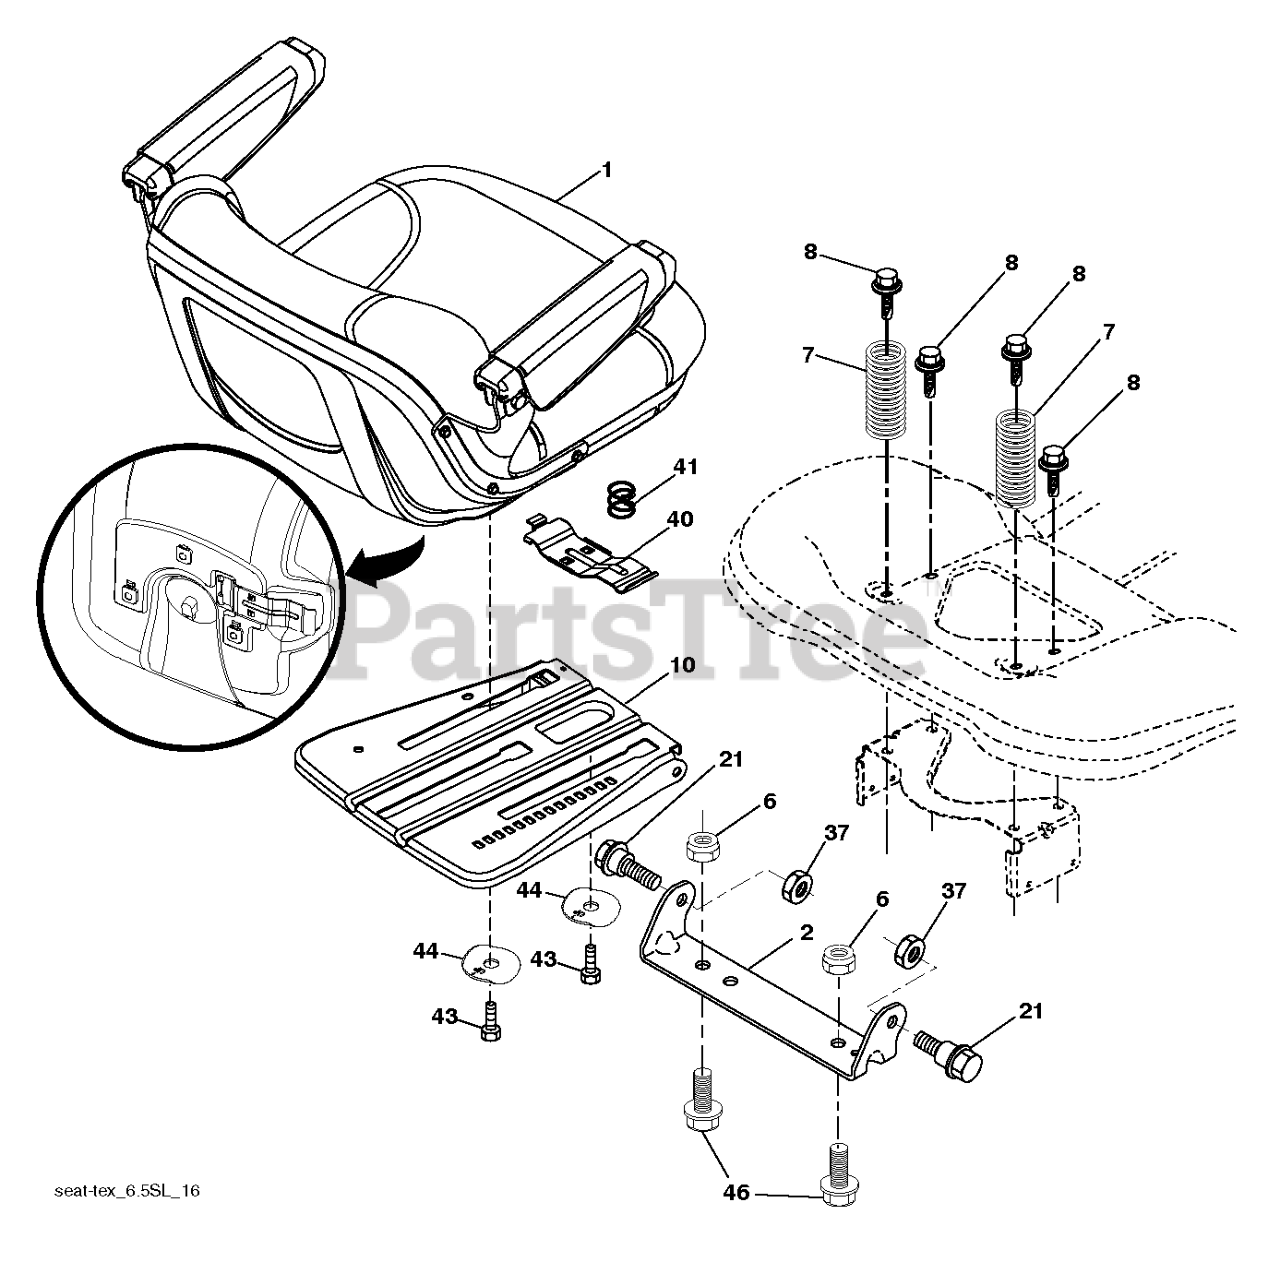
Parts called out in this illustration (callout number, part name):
1	SEAT.TH154.498GY.HUS.ARMRESTS
2	BRKT.PIVOT.FENDER
6	NUT
7	SPRING.COMPRESS.SEAT.TAPERED
8	BOLT.5/16-18UNCX3/4 W/SEMS.BLK
10	PLATE SEAT; SLIDE; 3PT BLACK;
21	BOLT.5/16-18X5/8.SHOULDER
37	NUT.71038.31-18.HEX.NYLOCK
40	HANDLE.SLIDE.SEAT.TEX.BLACK
41	SPRING.LATCH.SEAT.TEX
44	WASHER.WINGED.3/8ID.1.5OD
46	BOLT.3/8-16X1;1.25OD.WSHR.SEMS
